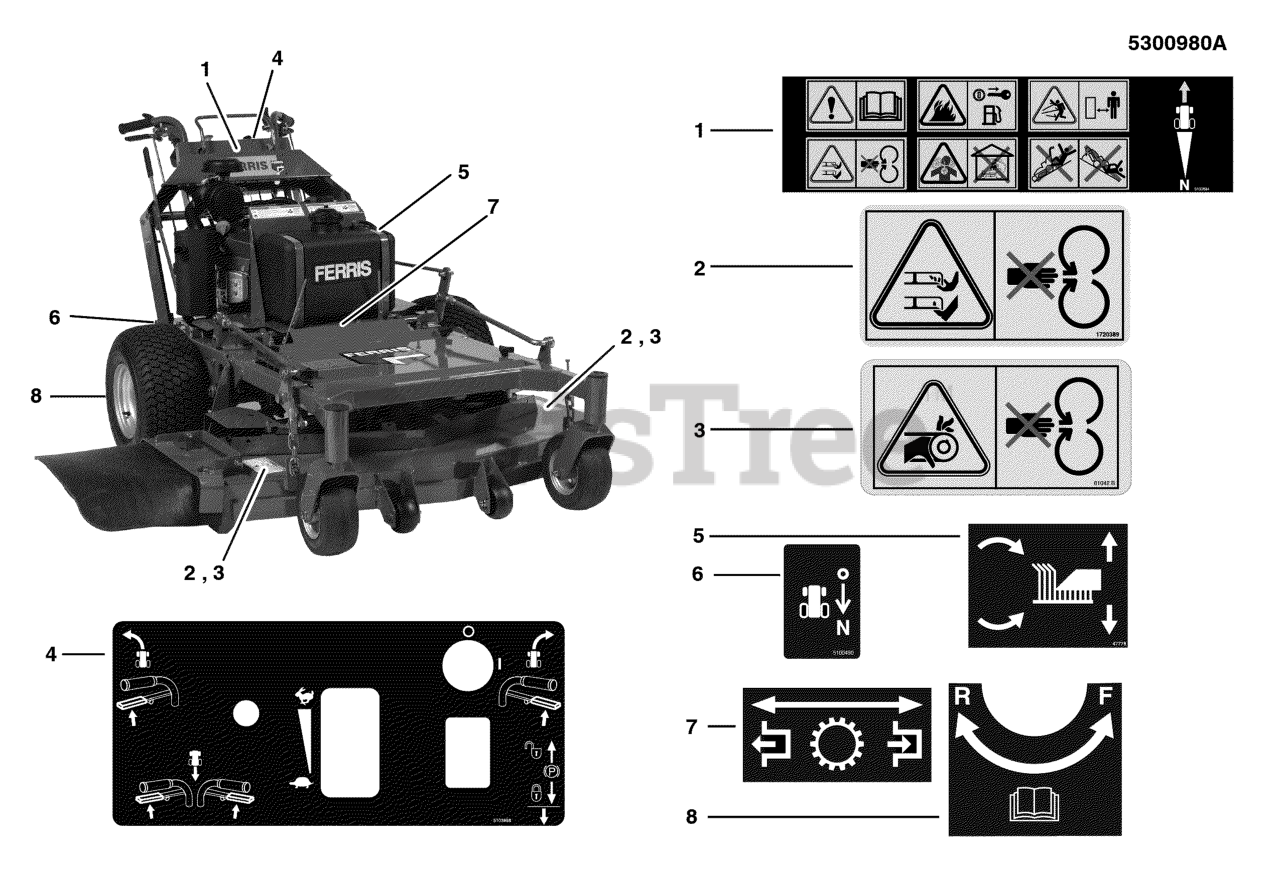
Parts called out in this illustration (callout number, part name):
1	DECAL, CCW, CE
2	DECAL, CE DANGER
3	DECAL-DANGER ROTATING BLADE SYMBOLS
4	DECAL, CONROL PANEL, WB
5	DECAL-CUT HEIGHT ADJUST HYDRO CUT
6	DECAL, PEDAL
7	DECAL, HYDRO RELEASE
8	DECAL, FORWARD / REVERSE
